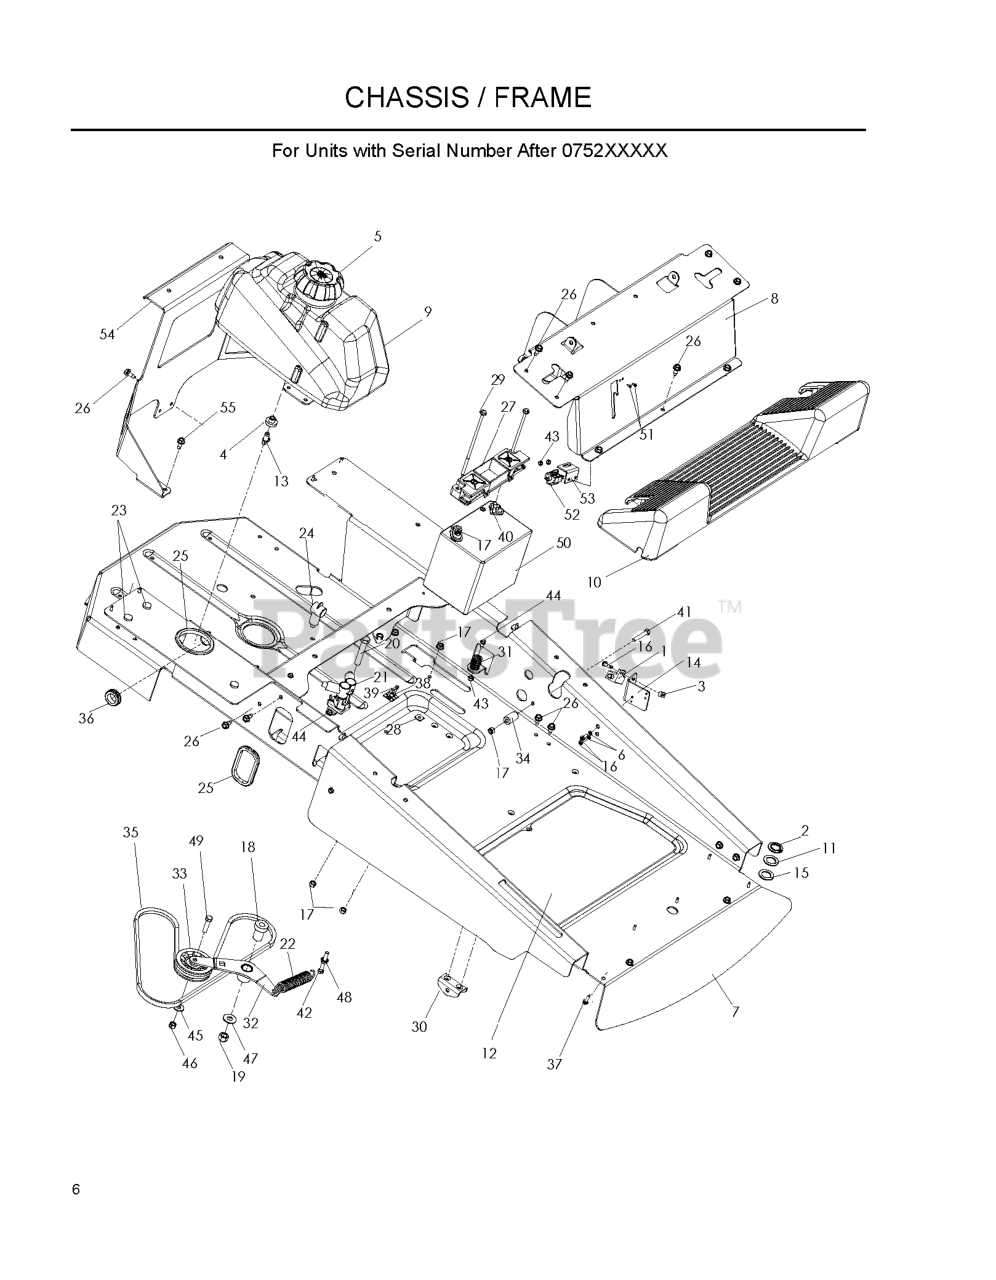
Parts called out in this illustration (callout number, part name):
1	SWITCH, INTERLOCK
2	RETAINING RING, 7/8"
3	TAPPED PLATE
4	RUBBER GROMMET
5	FUEL CAP ANTI-SPLASH
6	WASHER - 3/16 LOCK ZD
7	FRAME W/DECALS
8	CONSOLE W/DECALS
10	FOOT REST GRAY
12	SLIP, MATTING
13	STEM, FUEL TANK
15	BSHG .875 X 1.375 X .074 ZD
16	SCREW #10-24 X 5/8
17	NUT 5/16 NYLOC
18	IDLER SPINDLE
19	NUT 1/2-13 HEX NYLOC ZD
20	HCS 1/2C X 2 3/4
23	GROMMET, BUMPER
26	BOLT 5/16-18 X 3/4
27	BATTERY HOLD DOWN
28	PUSH NUT-NYLON
29	BOLT - 1/4-20 X 7.5
30	BRACKET, DECK HANGER
31	SPRING, RETURN TO NEUTRAL
32	PUMP IDLER WELDMENT
33	PULLEY, IDLER RAKE & ZTR
34	MOTION LIMITER
35	BELT, HYDRO PUMP
36	GROMMET, FUEL LINE
37	SCR #10-12X1-1/2HEX WASH HD ZD
38	MOUNTING BLOCK CABLE TIE
39	TIE, PLASTIC
40	HCS 5/16C X 3/4
41	HCS 5/16-18X2
43	NUT.1/4-20.HEX.NYLOC.ZD
44	SCREW 1/4 X 5/8
45	WASHER 3/8 FLAT
46	NUT 3/8C CENTERBLOCK
47	WASHER 1/2 FLAT
48	NUT 5/16C WHIZ
49	HCS 3/8C X 1 1/2
50	BATTERY, 12 V 330 AMP
51	HCS 1/4-20.
52	SWITCH, BRAKE 3P
53	BRACKET, BRAKE SWITCH
